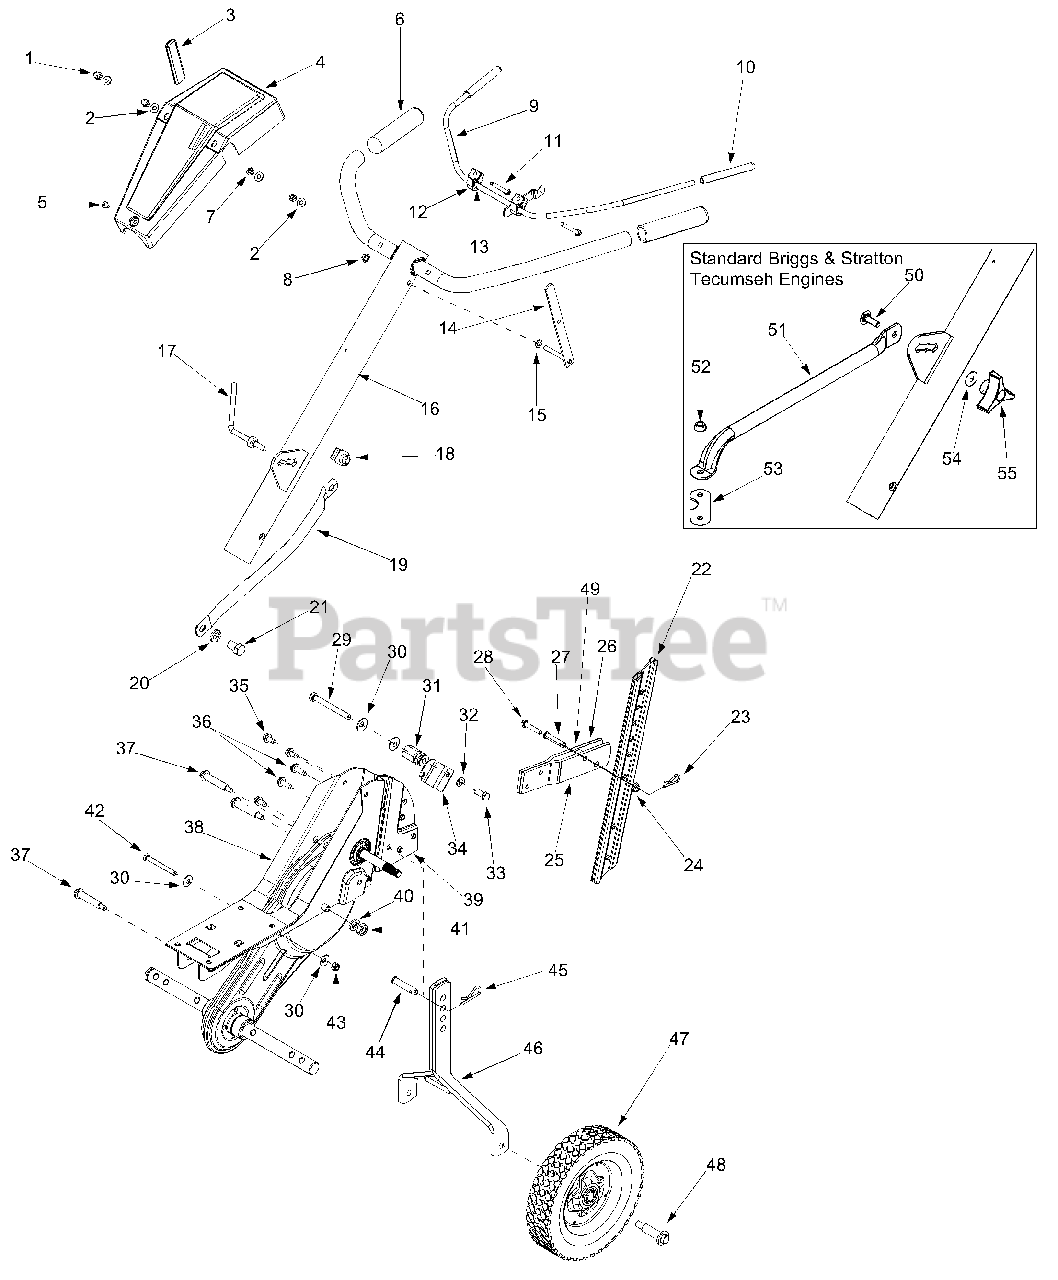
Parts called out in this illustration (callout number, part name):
1	Acorn Lock Nut 1/4-20
2	Flat Washer .271" I.D. x .630" O.D.
3	Reverse Handle Grip
4	Handle Cover w/o throttle
5	Truss Mach. Scr. #10 x 1/2" Lg.
6	Grip-Handle
7	Hex Nut 1/4-20 Gr.2
8	Cap Speed Nut
10	Grip-Clutch
11	Hex Bolt 1/4-20 x 2.25" Lg. Gr.5
12	Clutch Handle Holder
13	Flat Washer .385" I.D. x .62" O.D.
15	Flat Washer .344" I.D. x .62" O.D.
18	U Nut 5/16-18
21	Hex Bolt 1/2-20 Gr. 5
23	Cotter Pin
24	Hex Flange L-Nut 5/16-18 Thd. Gr.5
27	Clevis Pin
28	Hex Bolt 5/16-18 x 1.5" Lg.
29	Hex Bolt 5/16-18 x 3" Lg.
30	Wash. Bell. .340" I.D. x .872" O.D.
31	Spec. Hex Nut
32	L-Wash. 5/16" I.D.
33	Hex Bolt 5/16-18 Gr. 5
35	Hex Washer Screw 5/16-18 x .62" Lg.
36	Hex Wash. Hd. TT-Tap Scr.
37	Shdl. Bolt 5/16-18
40	Lock Washer 7/16
41	Jam Nut 7/16-20 Gr. 2
42	Hex Bolt 5/16-18 x 2.75" Lg.
43	Hex Nylon Nut 5/16-18 Thd.
44	Clevis Pin
45	Cotter Pin
47	Wheel Ass'y 8" x 1.75"
48	Shoulder Screw .496 I.D. x 1.445 O.D.
49	Spacer
50	Carr. Bolt 5/16-18 x 1
53	Engine Brkt. (Std. B&S)
54	Bell. Wash. .34" I.D.
55	Hand Knob
